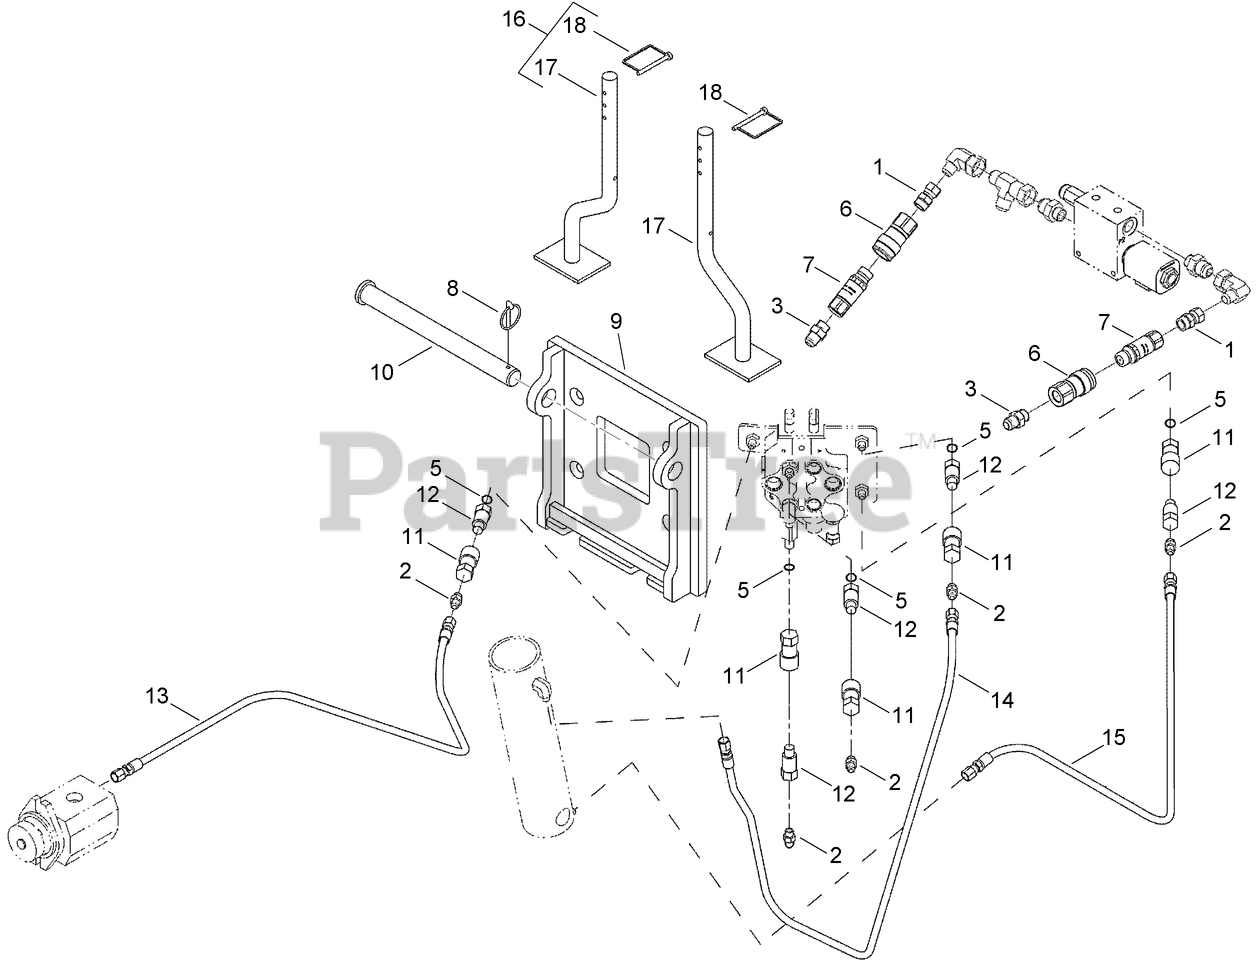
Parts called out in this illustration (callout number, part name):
1	ADAPTER - 5/8, SAE O-RING
2	CONNECTOR-Str Thd 3/8, 37FL-ORB 3/8
3	CONNECTOR-Str Thd 5/8, 37FL-ORB 5/8
5	O-RING - .062 x .562 in
6	COUPLER - 1/2 Female Quick Disconnect
7	COUPLER - 1/2 Male QD, Connect Under Press
8	PIN-KLIK
9	LOCKING WELDMENT - Quick Attach
10	PIN - Locking
11	COUPLER - Quick Disconnect
12	COUPLER - Quick Disconnect - Male 3/8
13	HOSE ASSEMBLY - Hydraulic
14	HOSE ASSEMBLY - Hydraulic
15	HOSE ASSEMBLY - Hydraulic
16	ASSEMBLY - Plow Stand
17	WELDMENT - Leg, Plow Stand
18	PIN - Snapper
